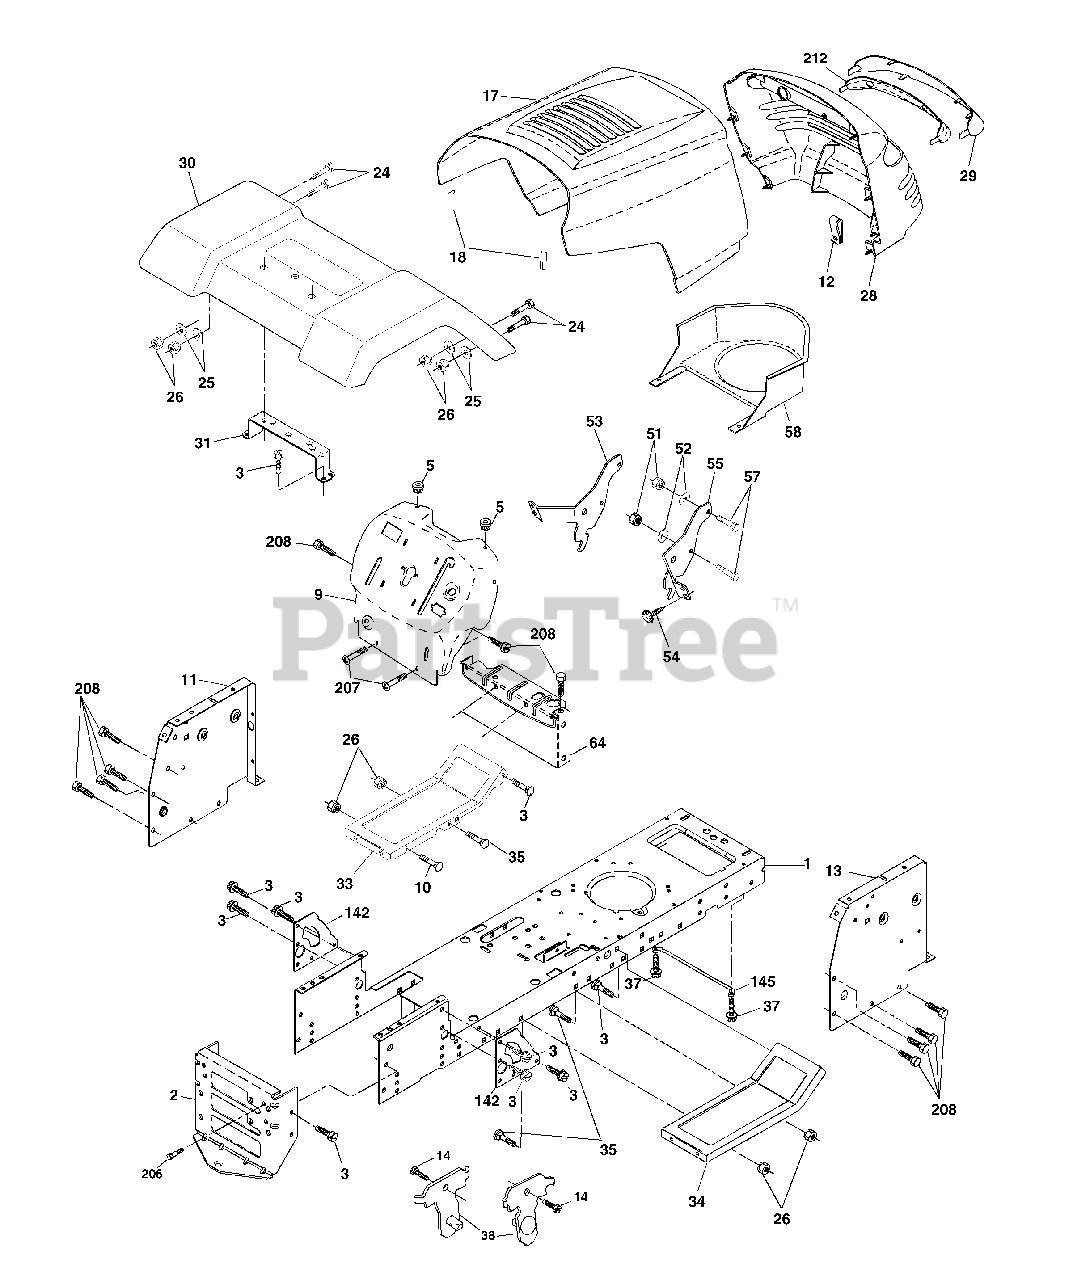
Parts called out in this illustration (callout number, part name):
1	Chassis
2	Drawbar, Stretch
3	Screw 3/8-16 x 3/4
5	Bumper, Hood/Dash
10	Bolt, Carriage 3/8-16 x 1
11	Panel Dash LH
12	Clip Tinnerman Grille P.L
13	Panel Slkscr Dash RH
14	Screw Thdrol 3/8-16 x 1/2
17	Hood
18	Bumper Hood
24	Bolt Fin Hex 3/8-16unc X 1 Gr. 5
25	Washer 13/32 X 13/16 X 12 Ga
26	Nut Lock Hex w/Ins 3/8-16 Unc
28	Grille/Lens Asm.
29	Lens Grille Private Label
30	Fender
31	Bracket Fender Repl 109873x
33	Footrest Pnt LH
34	Footrest Pnt RH
35	Bolt Rdhd Sht Sqnk 3/8-16 X3/4
37	Screw Thdrol 5/16-18 x 1/2 TYT
38	Bracket Asm. Pivot Mower
51	Nut Lock W/Insert 1/4-20unc
52	Washer 9/32 x 7/8x16 Ga.
53	Bracket Grille Lh
54	Screw Hex 8-18 x 7/8
55	Bracket Grille Rh
57	Bolt Fin Hex 1/4-20 unc x .75
58	Duct Air Engine PL/LT
64	Dash Lower
142	Plate Reinforcement
145	Rod Pivot Chassis/Hood
206	Bolt Shoulder 5/16-18
207	Screw Thdrol 5/16-18 x 1/2
208	Screw Thdrol 3/8-16 x 1/2
212	Insert Lens Reflect
